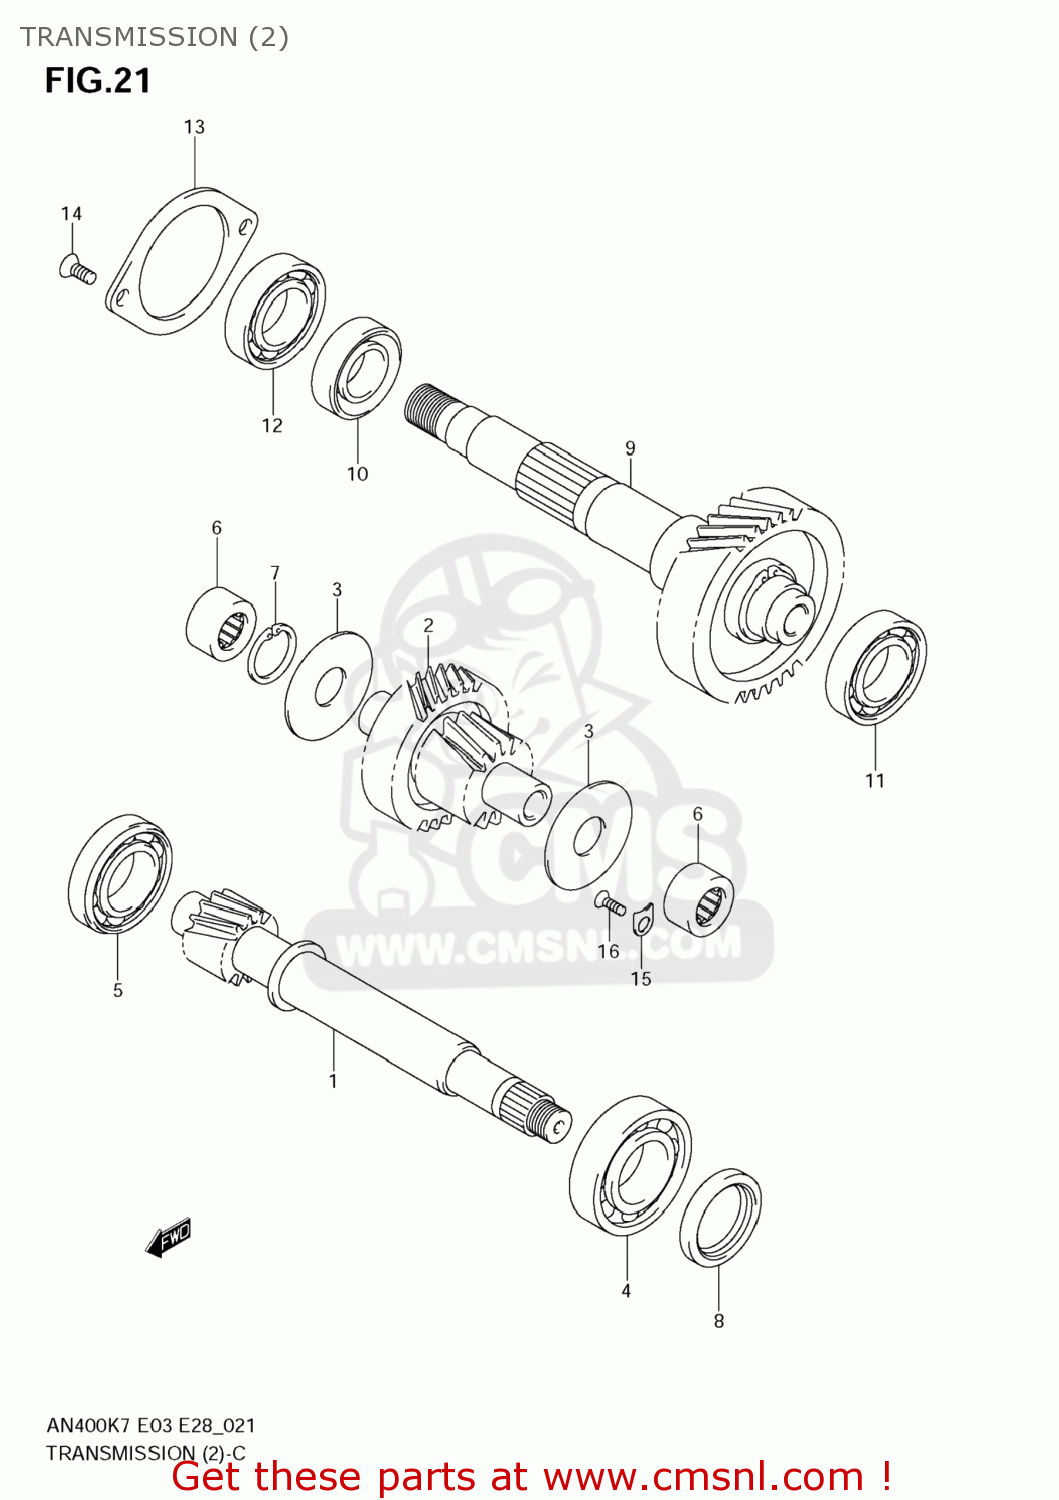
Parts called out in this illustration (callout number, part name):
1	SHAFT,DRIVE(NT:14)
2	SHAFT,IDLE(NT:15)
3	WASHER(20X50X2)
4	BEARING
5	BEARING(20X52X15)
6	BEARING(20X34X18)
7	CIRCLIP
8	SEAL,OIL(25X37X6)
9	SHAFT,RR AXLE(NT:40)
10	SEAL,OIL(38X52X7)
11	BEARING(25X62X17)
12	BEARING
13	RETAINER,AXLE SHAFT BEARING
14	SCREW
15	RETAINER
16	SCREW
